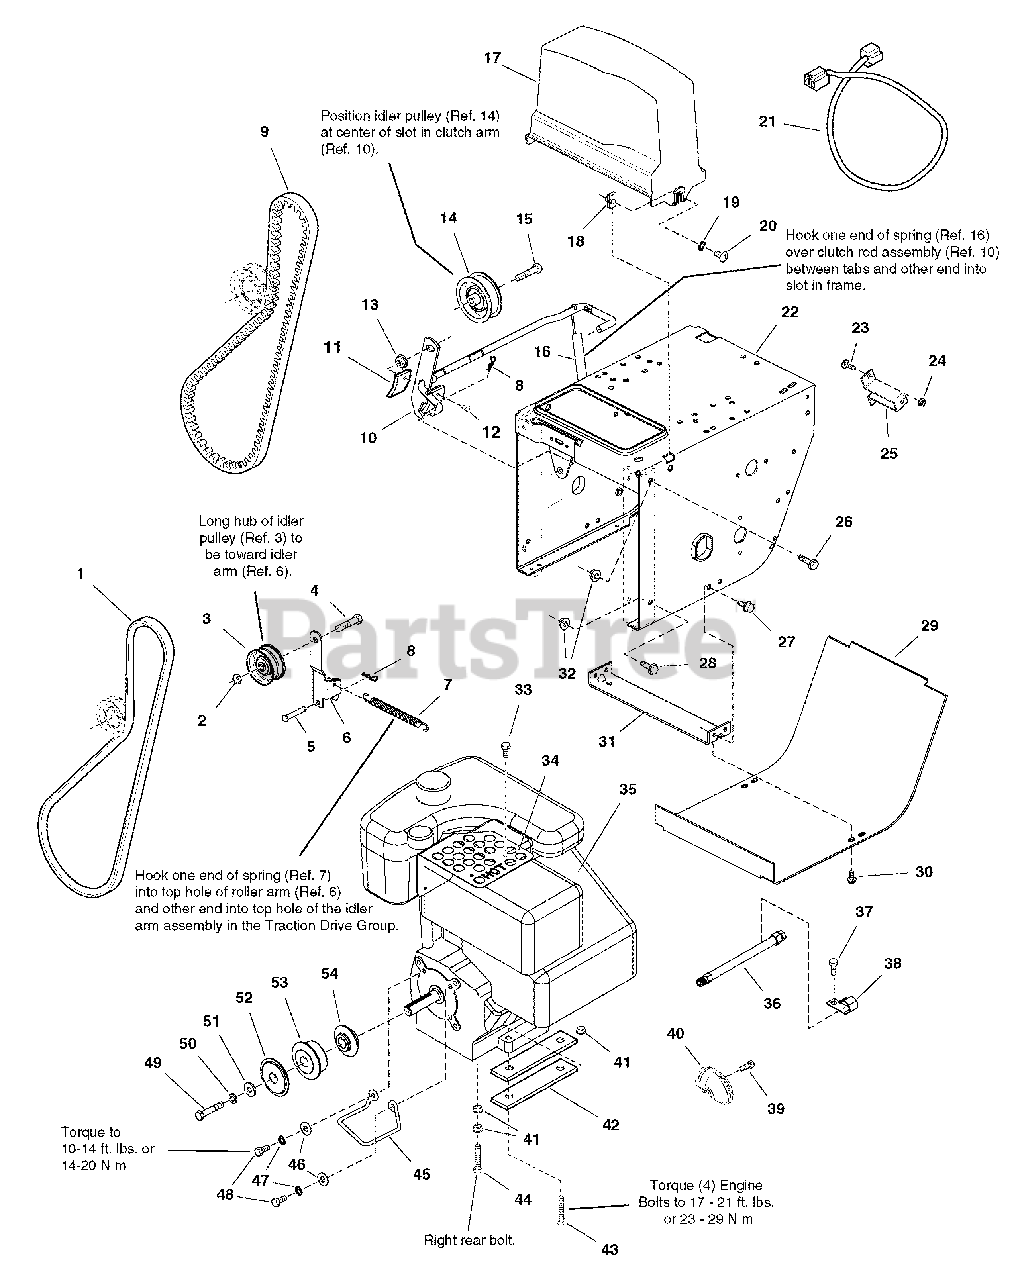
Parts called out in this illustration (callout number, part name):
1	V-BELT, 3L (Used on all models Except 1390 models)
1	V-BELT, 3L (Used Only on 1390 models)
2	NUT, Hex, Toplock, Jam, 3/8-16
3	PULLEY, Idler
4	SCREW, Hex Head, 3/8-16 x 1-1/2
5	PIN, Flat Head Drilled
6	ARM, Idler, 5-3/4 LG
7	SPRING, Extension
8	PIN, Quick
9	V-BELT, HA (Used on all models Except 1390 models)
9	V-BELT, HA (Used Only on 1390 models)
10	ROD AND ARM ASSEMBLY, Clutch, Brake w/Pad
11	PAD, Brake
12	RIVET, Pop
13	NUT, Hex Flange, 3/8-16 Whiz Lock Large
14	PULLEY, Idler
15	SCREW, Hex Whiz Lock Flange, 3/8-16 x 1-3/4
16	SPRING, Extension
17	COVER, Belt
18	NUT, Speed, Lug Type, 5/16-18
19	LOCKWASHER, External Tooth, 5/16
20	SCREW, Truss head Slotted, 5/16-18 x 3/4
21	CORD, Electric Extension
22	FRAME ASSEMBLY, Chain/Tube Handles
23	CARRIAGE BOLT, 1/4-20 x 3/4 G5
24	NUT, Hex KEPS, 1/4-20, Conical Washer
25	SUPPORT, Clutch Cable, 16GA
26	SCREW, Hex Whiz Lock Flange, 5/16-18 x 3/4
27	SCREW, Hex Washer Head Taptite, 5/16-18 x 3/4
28	SCREW, Hex Whiz, 5/16-18 x 1-1/4
29	COVER, Bottom Frame, 20GA
30	SCREW, Hex Washer Head Taptite, 1/4-20 x 1/2
31	SUPPORT, Tie Bar
32	NUT, Hex Flange, 5/16-18, Whiz Lock Large
33	SCREW, Hex Washer Head Taptite, #10-24 x 1/2
34	GUARD, Muffler, 18GA
35	ENGINE, 9/12HP Briggs & Stratton Electric Start
36	HOSE, Oil Drain, w/Fittings
37	CAPSCREW, Hex Washer Head, 5/16-18 x 3/4
38	CLIP, "J"
39	SCREW, Muffler Deflector
40	DEFLECTOR, Rain Guard, B&S Snow Muffler
41	NUT, Hex Flange, 5/16-18, Whiz Lock Small (Quantity 4 used only on 9560 models)
42	SUPPORT, Engine Riser, 3/8" Thick, 1-1/4 x 4-31/50 (Used on all models Except 1390 models)
43	CAPSCREW, Hex Whiz Lock Flange, 5/16-18 x 2-1/4 (Used on all models Except 1390 models)
43	CAPSCREW, Hex Head, 5/16-18 x 1-1/2 G5 (Used only on 1390 models)
44	CAPSCREW, Hex Washer Head Taptite, 5/16-18 x 2-1/2 (Used on all models Except 1390 models)
44	SCREW, Hex Head Cap, 5/16-18 x 1 3/4
45	STOP, Belt
46	WASHER, 5/16
47	LOCKWASHER, Spring, 5/16
48	CAPSCREW, Hex Head, 5/16-24 x 3/4 G5
49	CAPSCREW, Hex Head, 3/8-24 x 1-1/2 G8
50	LOCKWASHER, Spring, 3/8
51	WASHER, 3/8
52	PULLEY, Engine Outside, Powdered Metal
53	PULLEY, Engine Middle, Powdered Metal
54	PULLEY, Half Powdered Metal
